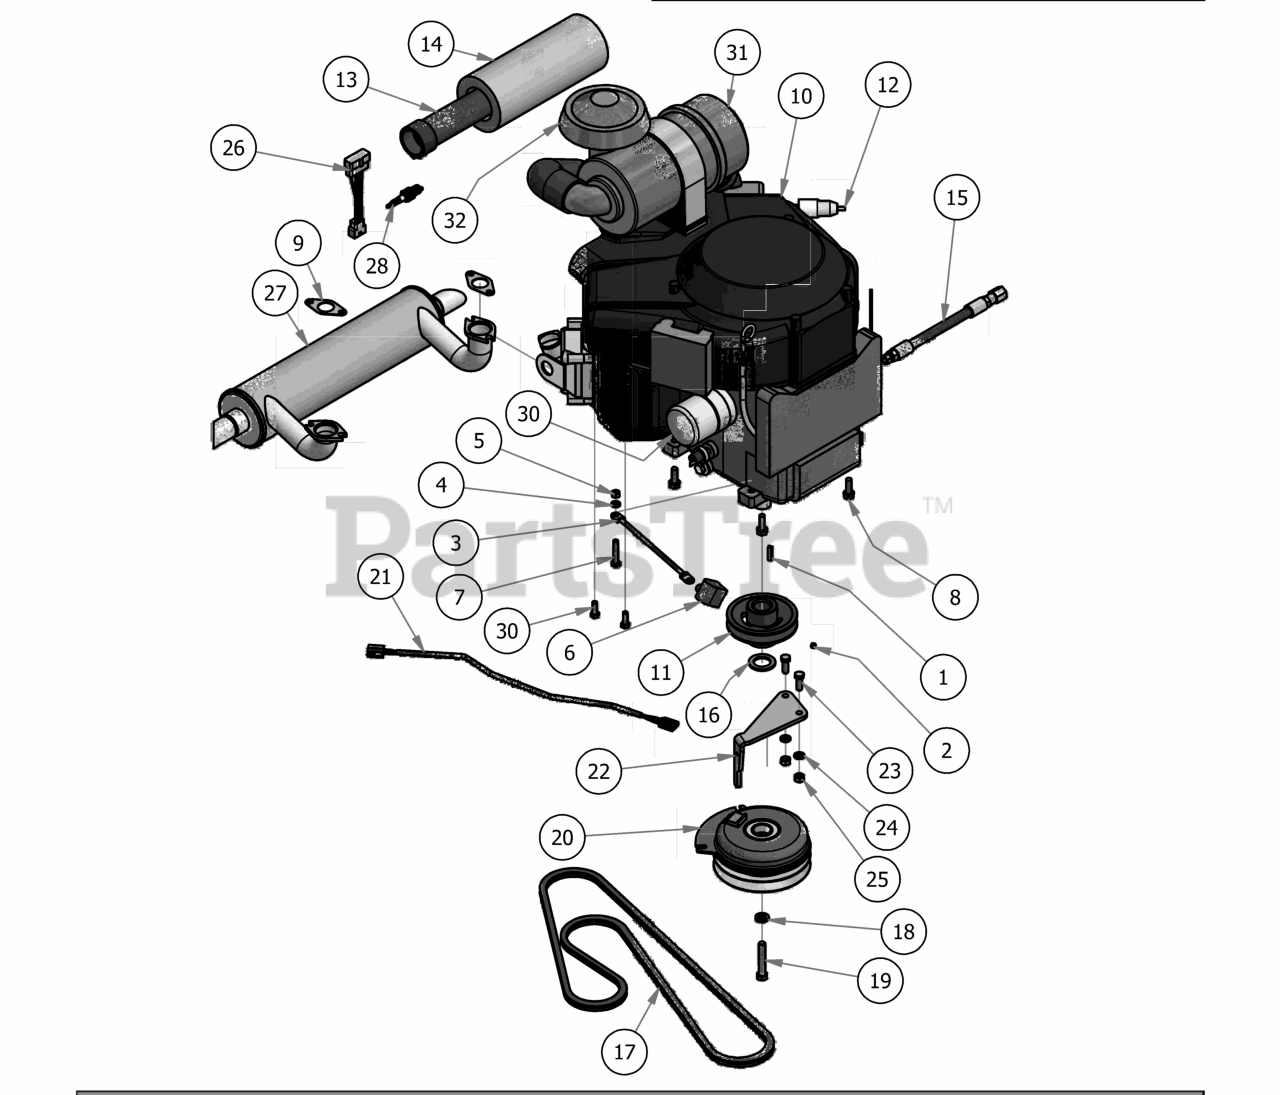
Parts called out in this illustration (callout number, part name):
1	1/4" x 1" Key
2	5/16 Set Screw
3	Ground Cable
4	5/16" Lock Washer
6	Black Boot For Ground Cable
7	5/16" x 1 3/4" Hex Bolt
8	3/8 x 1 1/8 bolt
9	Exhaust Gasket for 23 Vanguard
10	993cc Briggs Vanguard Engine
11	4 3/4 Motor Pulley
12	Universal Inline Fuel Filter
13	Canister Air Filter- Inner
14	Canister Air Filter- Outer
15	14 mm Oil drain Hose 993cc Vanguard
16	1 1/8" Flat Spacer
18	7/16" Lock Washer
19	7/16" x 2 1/2" Hex Bolt
20	Clutch Assembly
21	Clutch Pigtail
22	PTO Engager Holder
23	3/8" x 1" Hex Bolt
24	3/8" Lock Washer
25	3/8" Hex Nut
26	Harness Adaptor - 933cc Vanguard
27	2015 Exhaust - 36hp Vanguard
28	Spark Plug
30	Torx Bolt-Exhaust
30	Briggs Oil Filter
31	Complete Canister
32	Rain Cap Fits all Canisters
